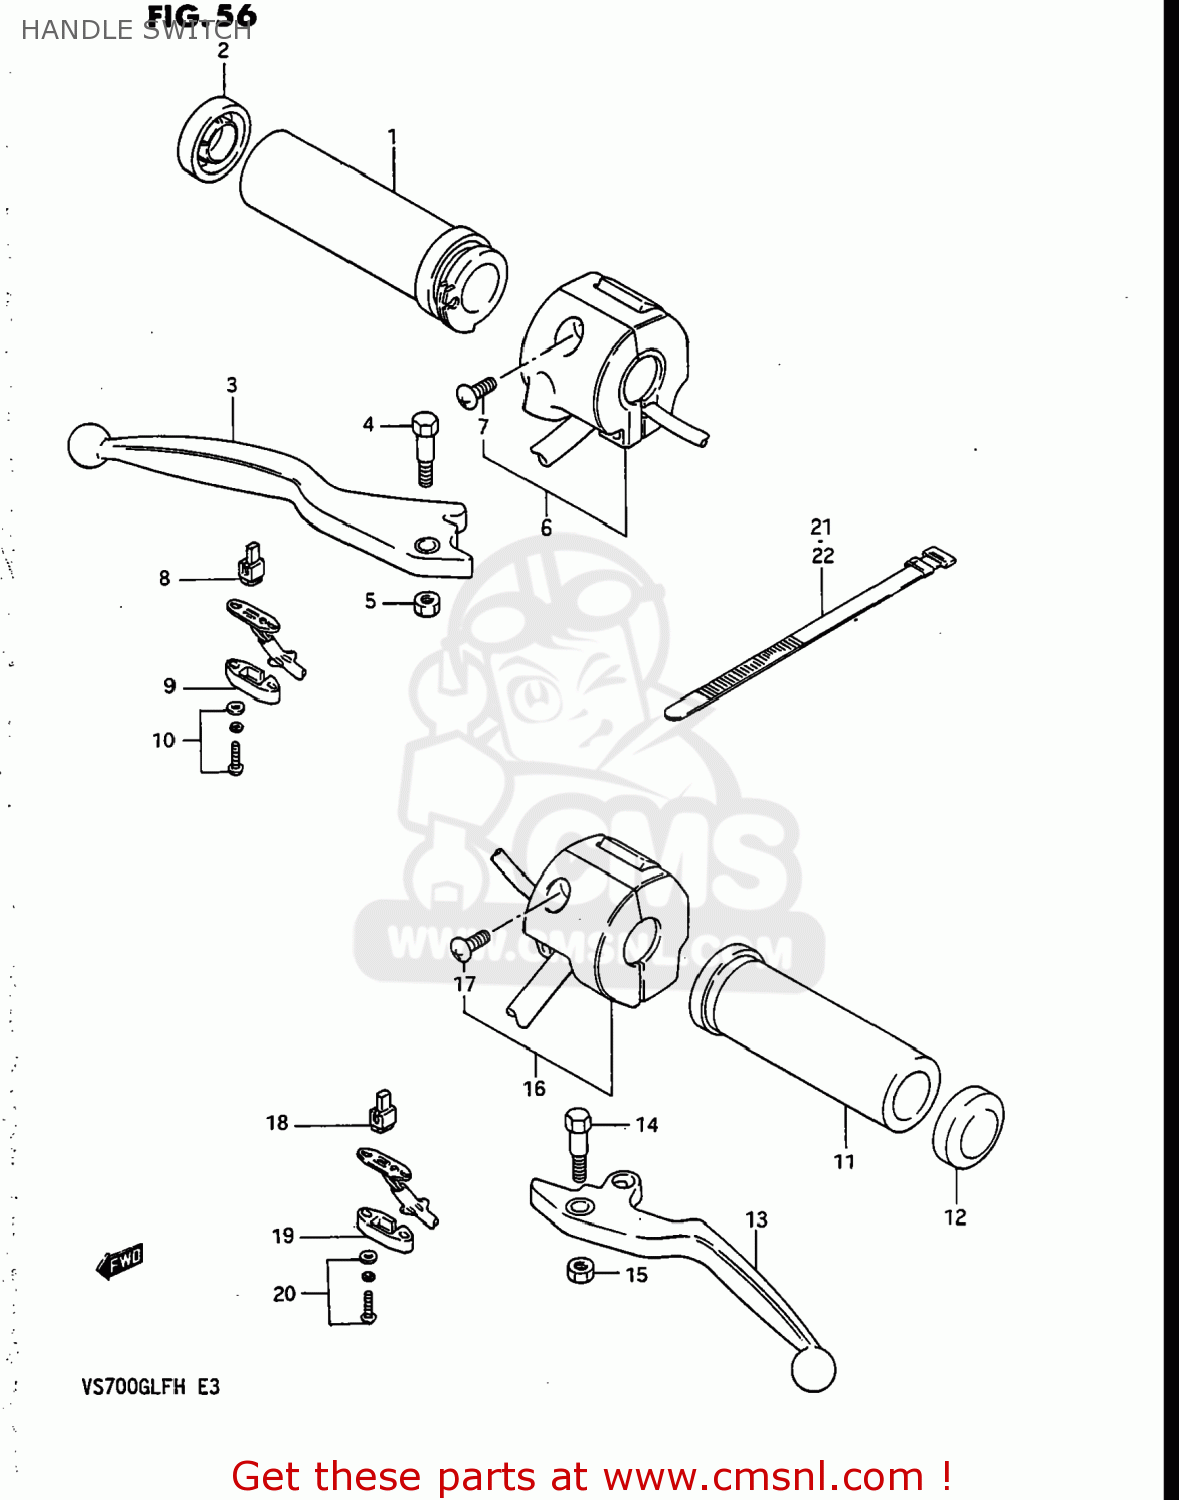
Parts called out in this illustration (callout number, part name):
1	GRIP,THROTTLE
2	CAP,GRIP END
3	LEVER,BRAKE
4	BOLT,LEVER
5	NUT 6MM
6	SWITCH ASSEMBLY,HANDLE,RIGHT
7	SCREW
8	CONTACT,SWITCH
9	COVER,BRAKE SWITCH
10	SCREW
11	GRIP,LEFT
12	CAP,GRIP END
13	LEVER,CLUTCH (SILVER)
14	BOLT,LEVER
15	NUT 6MM
16	SWITCH ASSEMBLY,HANDLE,LEFT
17	SCREW
18	CONTACT,SWITCH
19	COVER,CLUTCH SWITCH
20	SCREW
21	CLAMP
22	CLAMP
